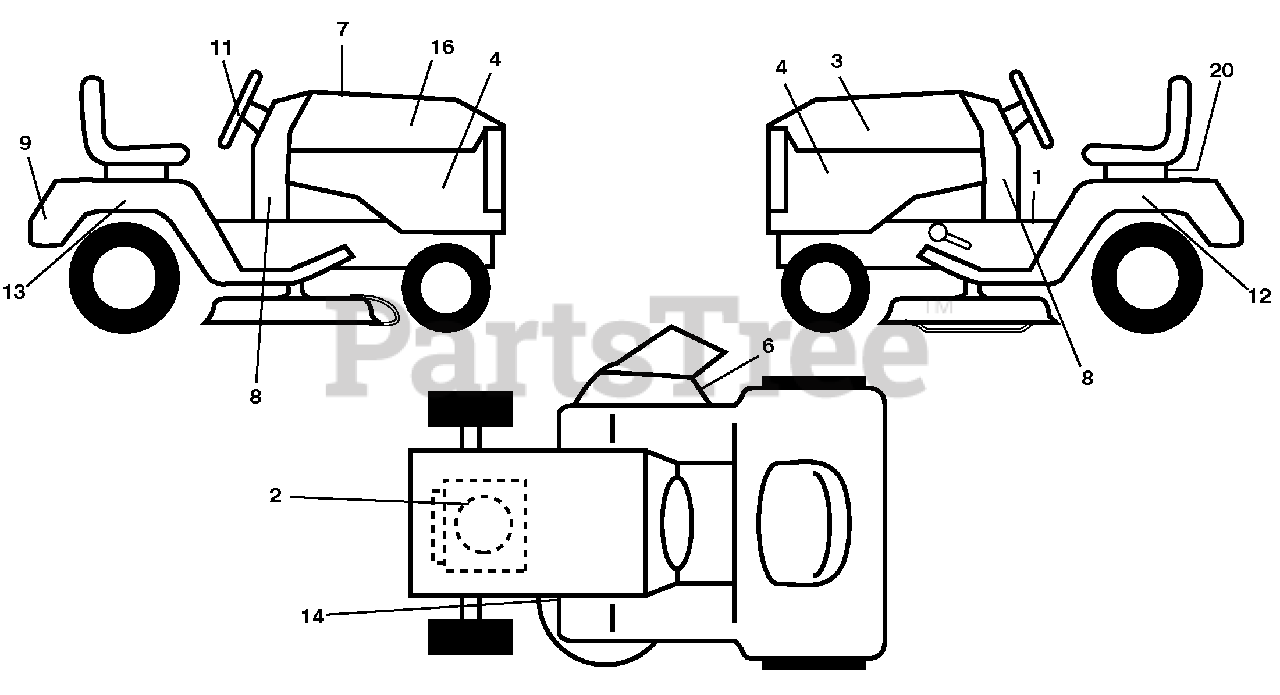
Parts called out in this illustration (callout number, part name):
1	Decal Fender Warning
2	Decal Engine H.P.
3	Decal Hood LH
4	Decal Side Panel
6	Decal Warning, Keep Hand Away
7	Decal Replacement Parts
8	Decal LWRDASH
9	Decal Fender Logo
11	Decal Ins Strg Whl
12	Decal Fender SD RH
13	Decal Fender SD LH
14	Decal V-Belt Schematic
16	Decal Hood RH
20	Decal Bat Dan/Psn
20	Pad Footrest LH
20	Pad Footrest RH
20	Decal Bypass
20	Manual Operator's E&F
20	Manual Parts
